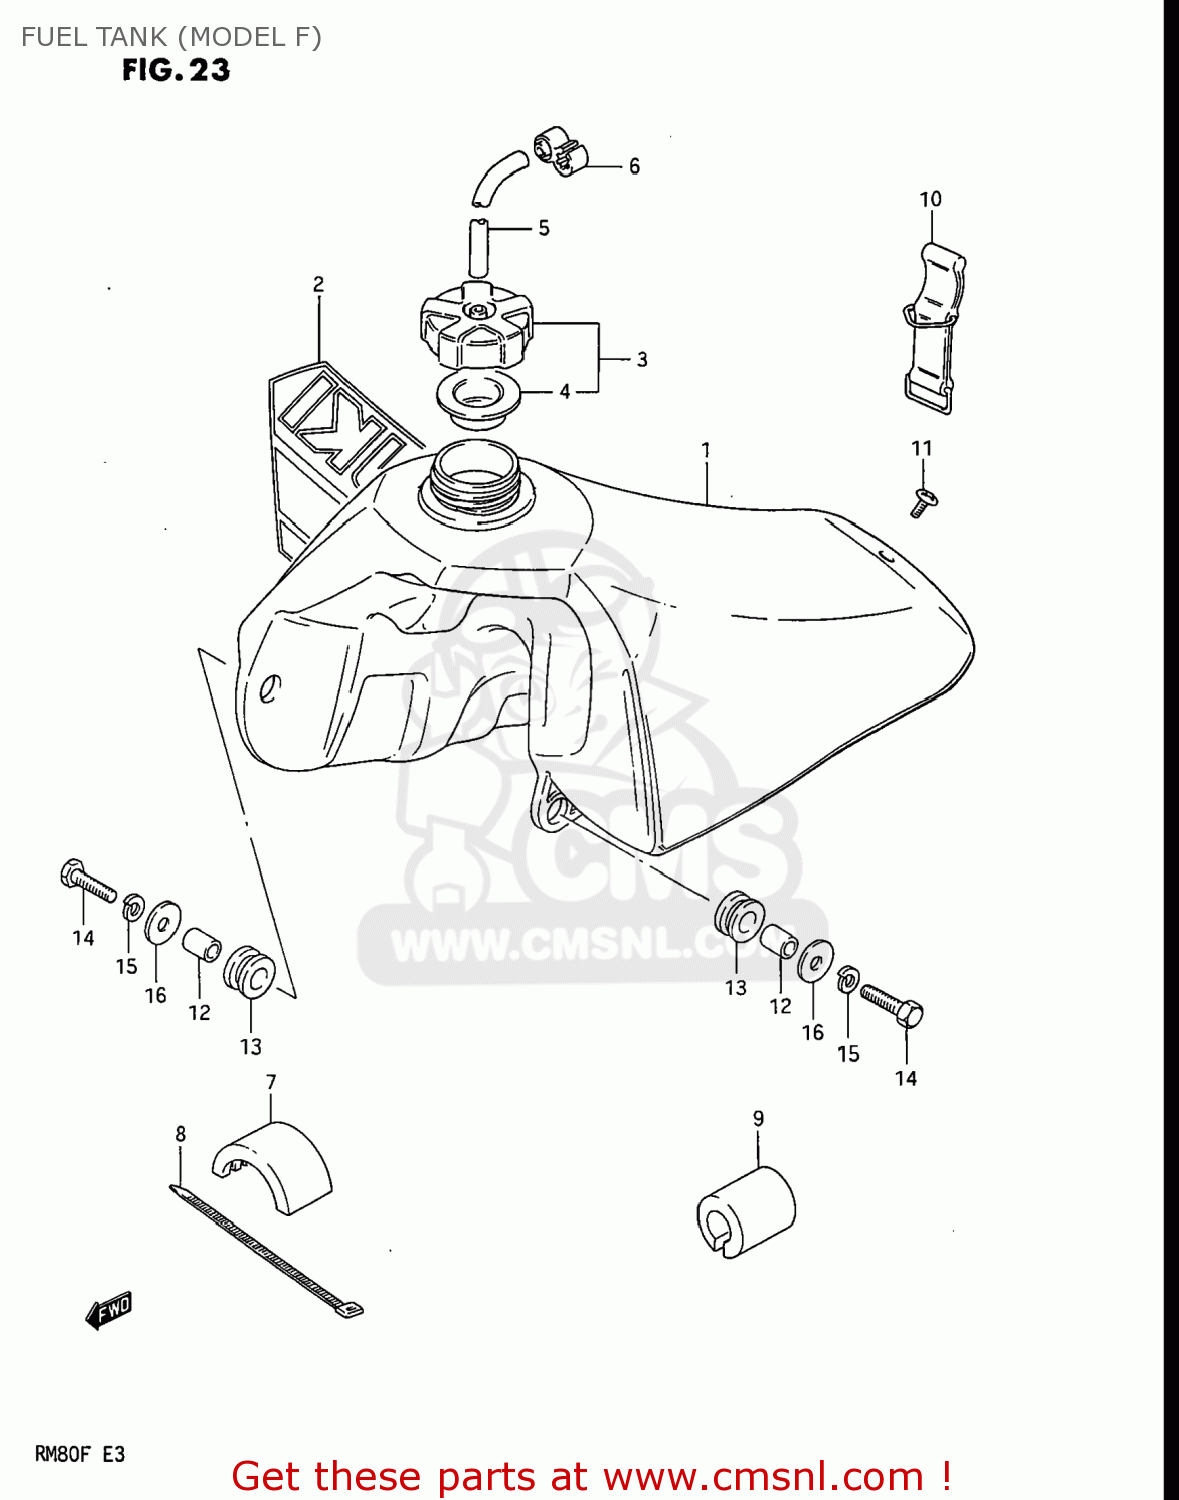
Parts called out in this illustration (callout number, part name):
1	TANK,FUEL
2	TAPE SET,FUEL TANK
3	CAP SET,FUEL TANK
4	GASKET,FUEL TANK CAP (NAS)
5	HOSE
6	CLAMP,FUEL TANK BREATHER HOSE
7	CUSHION,FUEL TANK UPR FR
8	CLAMP
9	CUSHION,FUEL TANK UPR RR
10	BAND
11	SCREW (6X15)
12	SPACER (6.8X10X11.5)
13	CUSHION
14	BOLT
15	WASHER,LOCK
16	WASHER (6.5X24X1.6)
